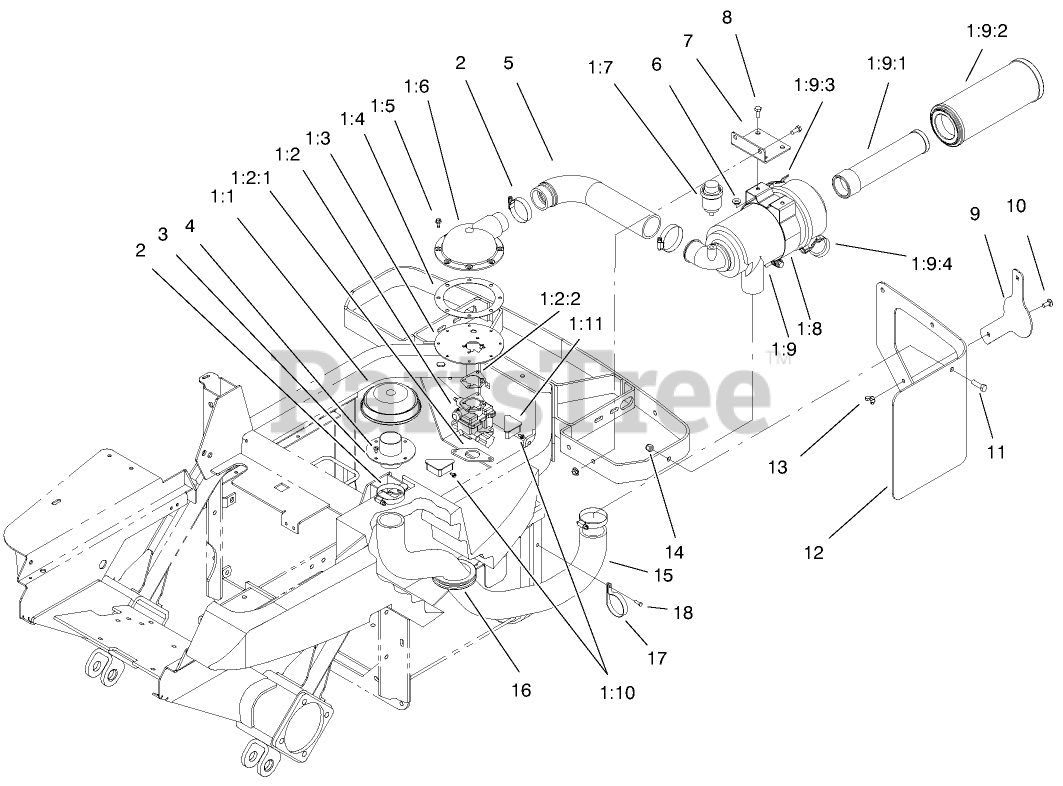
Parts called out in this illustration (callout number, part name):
1:1	Hood
1:2	Carburetor Kit (only on:100-2402)
1:2	Carburetor Kit (only on:100-2403)
1:2	Carburetor Kit (only on:100-2404)
1:2:1	Gasket
1:2:2	Gasket
1:3	Plate-Adapter
1:4	Gasket
1:5	Screw
1:6	Adapter
1:7	FILTER MINDER
1:8	Bracket-Air Cleaner
1:9	Air Cleaner ASM
1:9:1	Filter-Safety
1:9:2	Element-A/C
1:9:3	CLIP-CLEANER, AIR
1:9:4	VALVE-EJECTOR, DUST
1:10	Screw
1:11	Plug
2	CLAMP-HOSE
3	FLANGED CONNECTOR ASM
6	NUT-HF
8	SCREW-HH
9	PLATE - COVER
10	SCREW-CARR
11	SCREW-HH
13	NUT-WING
14	NUT-LOCK, NI
16	GROMMET-RUBBER
17	CLAMP-R
18	SCREW-HWHTF
